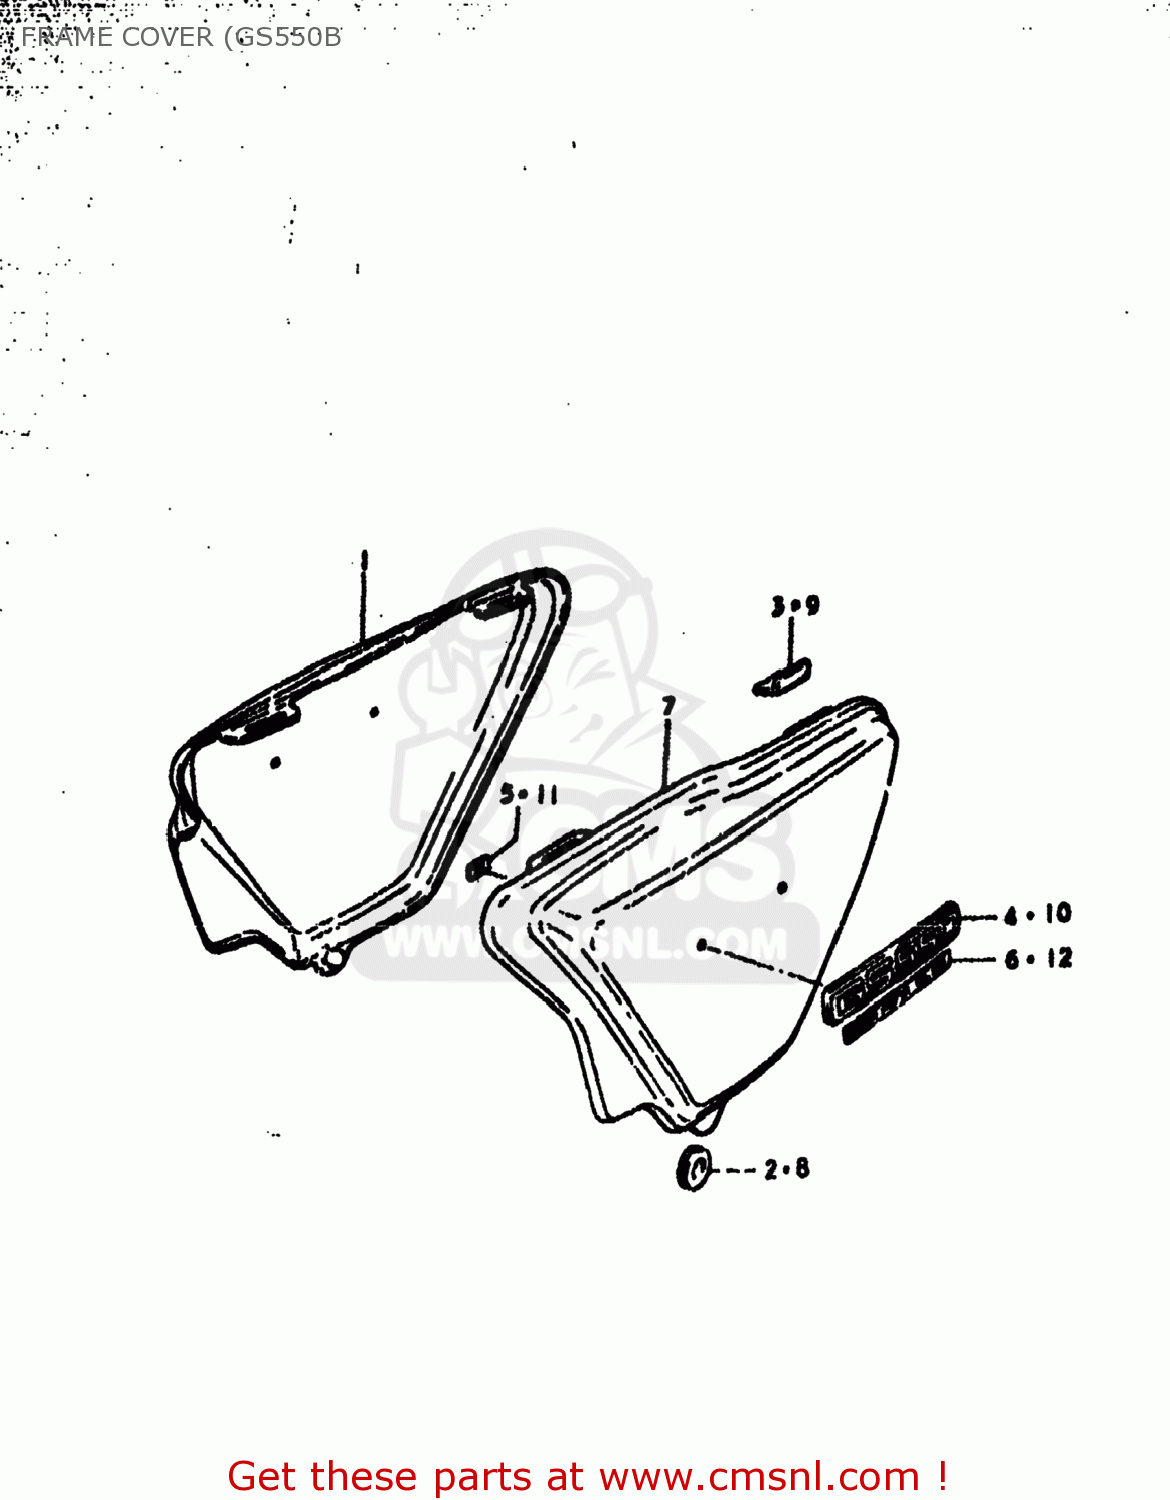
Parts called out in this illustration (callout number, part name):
1	COVER,FRAME,RIGHT
2	CUSHION
3	CUSHION,FRAME COVER
4	EMBLEM,FRAME COVER
5	NUT
6	LABEL,COMPANY NAME
7	COVER,FRAME,LEFT
8	CUSHION
9	CUSHION,FRAME COVER
10	EMBLEM,FRAME COVER
11	NUT
12	LABEL,COMPANY NAME
